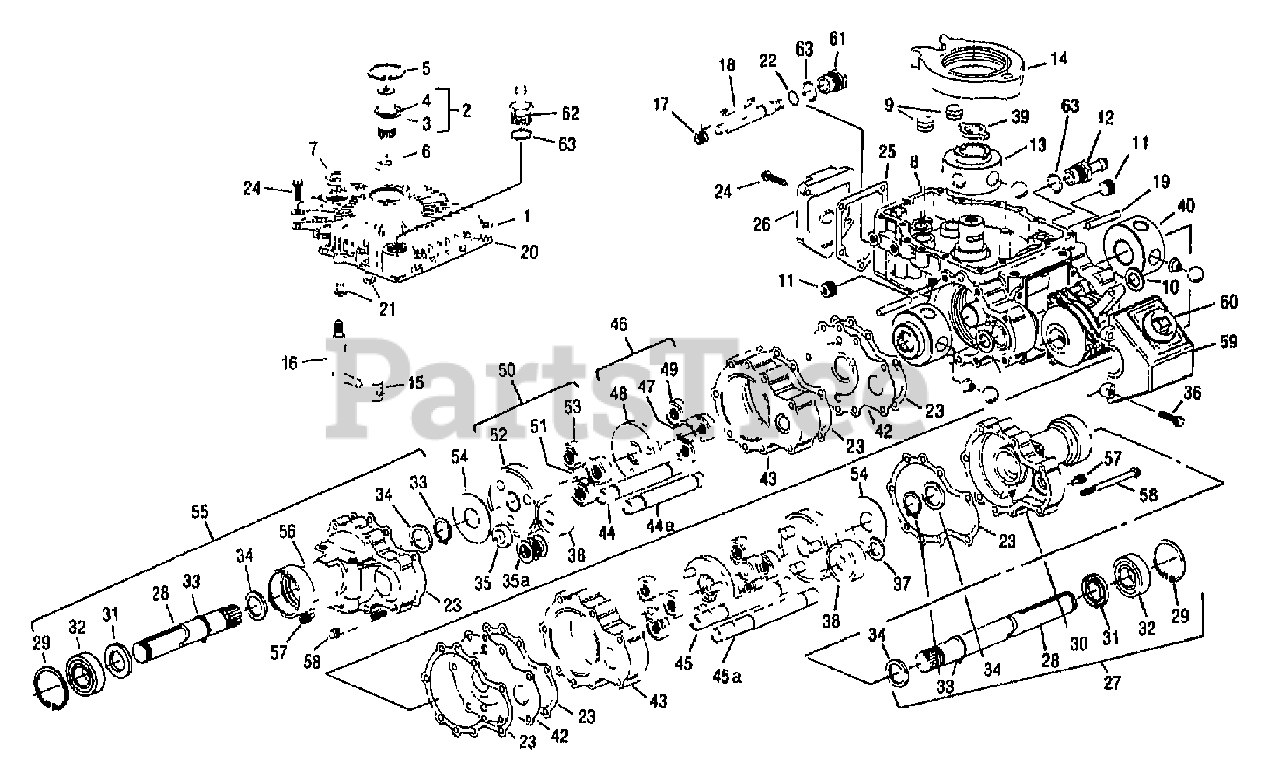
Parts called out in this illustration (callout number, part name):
1	Cover, Subassembly (S/A)
2	Shaft, Input, S/A
3	Bearing Input Shaft
4	Ring, Retaining, External
5	Ring, Retaining, Internal
6	Seal, Input Shaft
7	Seal Control Shaft
8	Housing, S/A CW
9	Piston, Dampening, S/A
10	Seal, Brake Shaft
11	Plug. Socket Pipe
12	Adapter Reservoir, 3/8 I D Tube
13	Pump Rotor-Ball, S/A
14	Cam Ring, S/A
15	Insert
16	Control Shaft S/A
17	Spring, Dump Valve
18	Bracket, Dump Valve
19	Dowel
20	Gasket, Cover
21	Button
22	O-Ring Dump Valve Bracket
23	Gasket, Axle Housing
24	Screw, 1/4-20 Hex Flange
25	Gasket, Valve Cover
26	Cover, Valve
27	Axle Housing, S/A-B
28	Shaft, Axle
29	Retaining Ring, Internal
30	Housing, Axle-B
31	Seal, Axle Shaft
32	Bearing, Axle Shaft
33	Retaining Ring External
34	Washer, Thrust
35	Spacer (Thick-PB)
35A	Washer, Thrust (DUPE)
35A	Bearing, Thrust (DL/PB)
36	Screw, 1/4-20 Self Tap
37	Spacer (Thin-PB or DUPE)
38	Brake Gear
39	Drive
40	Motor Rotor-Ball, A & B S/A, 1 BT
41	Differential Lock/Parking Brake Assembly
42	Plate, Wear
44	Brake Shaft-A (PB)
44A	Brake Shaft-A (DUPE)
45	Brake Shaft - B (PS)
45A	Brake Shaft - B (DUPE)
46	Planetary Gear, First A & B S/A
50	Planetary Gear, Second, A & B S/A
52	Secondary Carrier, A & B S/A
54	Washer, Thrust
55	Axle Housing, S/A-A
56	Housing, Axle-A
57	Plug, Magnetic
58	Screw, 1/4-20 Hex Flange
59	Cover, (PB or DUPE)
60	Boot, Dust
61	Nut, Dump Valve
62	Adapter, Reservoir, 3/8 I D Tube
63	O-Ring
